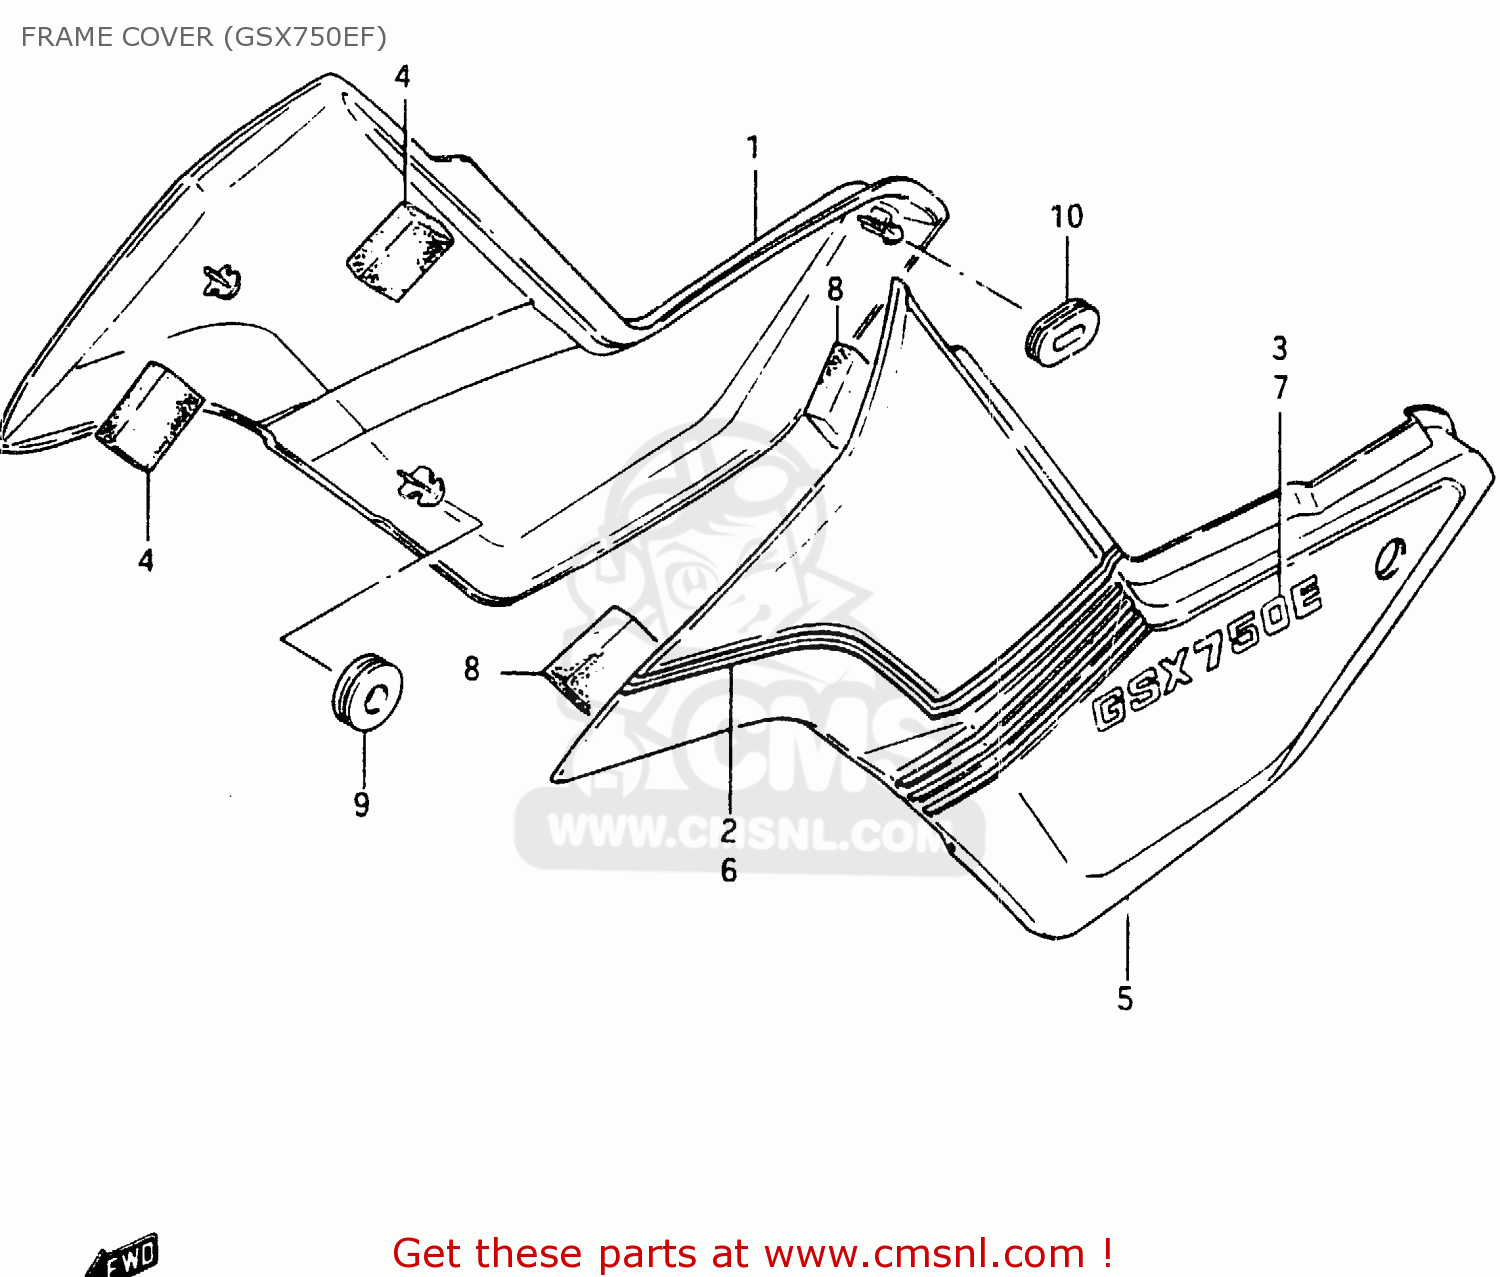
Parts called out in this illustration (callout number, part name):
1	COVER, FRAME RH
2	TAPE SET, FRAME COVER RH
3	EMBLEM
4	CUSHION
5	COVER, FRAME LH
6	TAPE SET, FRAME COVER LH
7	EMBLEM
8	CUSHION
9	CUSHION
10	CUSHION
